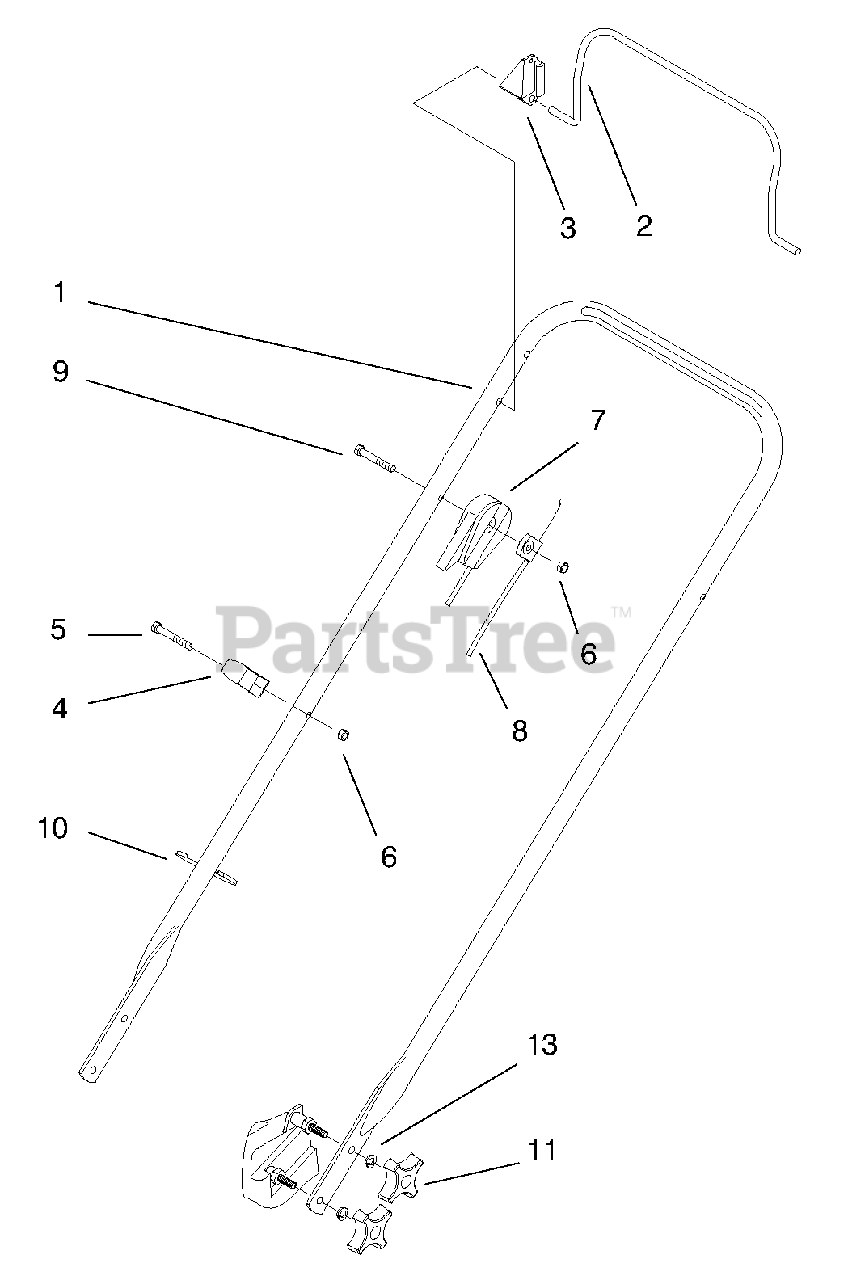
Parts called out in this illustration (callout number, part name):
2	Bail-Flywheel Brake
3	Stop-Pivot
4	Guide-Rope
5	Screw-HH
6	Nut-Lock Insert
7	Cable Throttle
8	Cable-Flywheel Brake
9	Screw-HH
10	Tie-Cable
11	Knob
13	Washer-Lock
